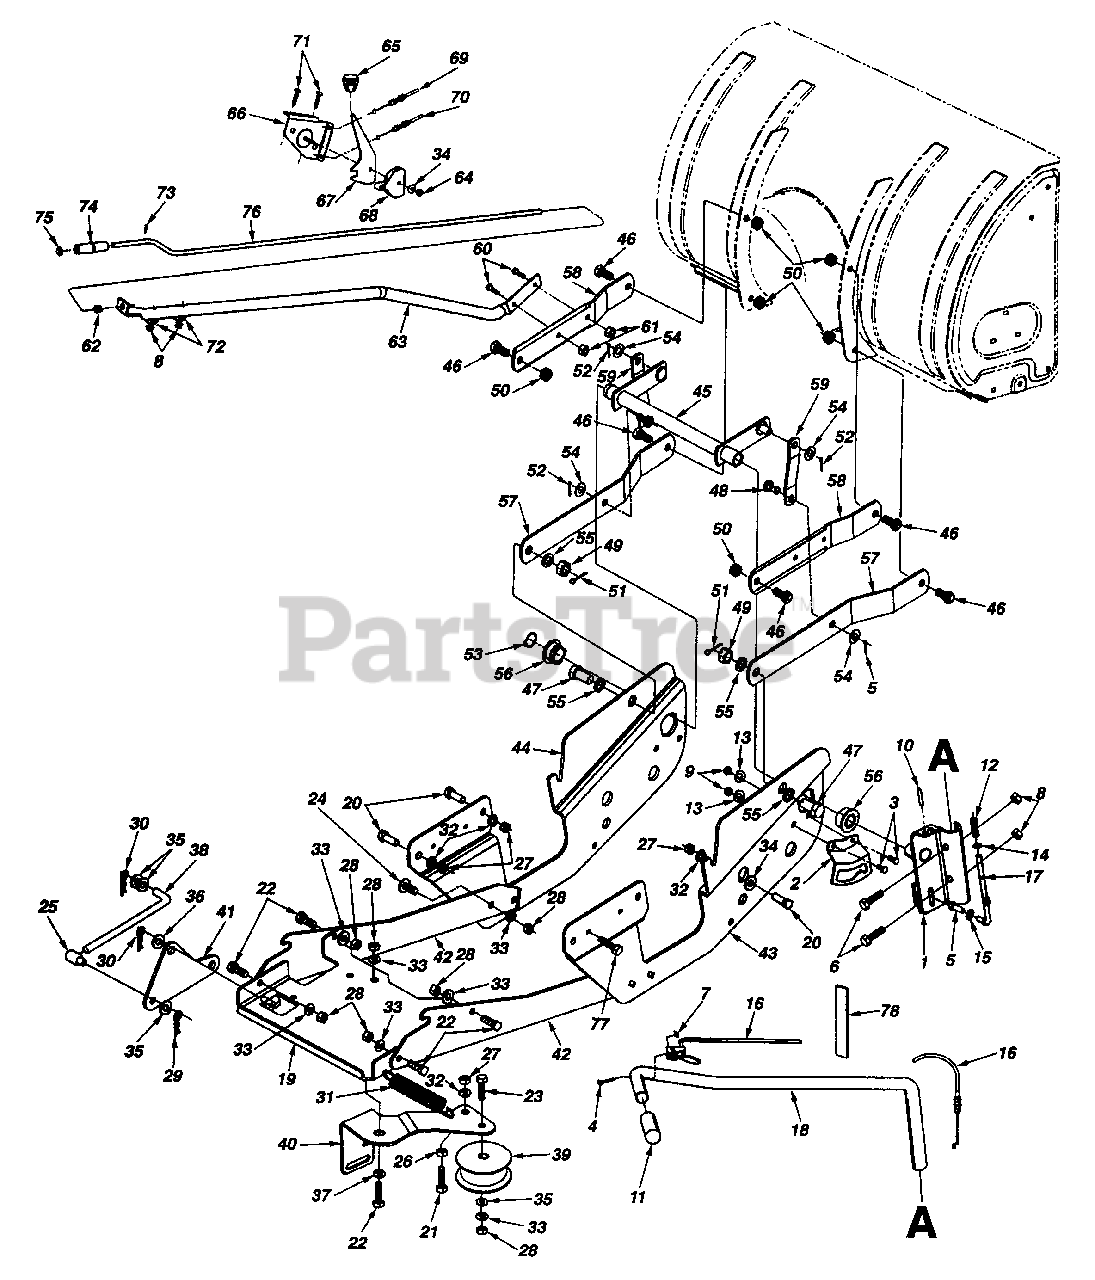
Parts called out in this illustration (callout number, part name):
4	Oval C-Sunk Scr. #10-24 x 1.36" Lg.
5	Hex Wash. Hd. Scr. 5/16-18 x .87" Lg.
6	Hex Bolt 5/16-18 x 1.75" Lg.
7	Flat Weld Nut #10-24 Thd.
8	Hex Flange L-Nut 5/16-18 Thd.
9	Hex Nut 5/16-18 Thd. (Gr. 5)
10	Spring Pin 1.5" Lg.
12	Ext. Spring 1.75" Lg.
13	L-Wash. 5/16" I.D.
14	Fl-Wash. .385" I.D. x .62" O.D.
15	Fl-Wash. .194" I.D. x .62" O.D.
16	Lift Cable
17	Lift Index Rod
18	Lift Handle Tube
21	Hex Bolt 5/16-18 x 2.25" Lg.
22	Hex Bolt 3/8-16 x 1" Lg.
23	Hex Bolt 3/8-16 x 2" Lg. (Gr. 5)
24	Carriage Bolt 3/8-16 x 1" Lg. (Gr. 5)
25	Ferrule 3/8-24 Thd.
26	Hex Jam Nut 5/16-18 Thd.
27	Hex Nut 5/16-18 Thd. (Gr. 5)
28	Hex Nut 3/8-16 Thd. (Gr. 5)
29	Hairpin Clip 1.42" Lg.
30	Hairpin Clip 1.62" Lg.
31	Ext. Spring 5.5" Lg.
32	L-Wash. 5/16" I.D.
33	L-Wash. 3/8" I.D.
34	Bell-Wash. .345" I.D. x .88" O.D.
35	Fl-Wash. .406" I.D. x .875" O.D.
36	Fl-Wash. .531" I.D. x 1" O.D.
37	Shoulder Spacer
38	Adj. Clutch Control Rod
39	Idler Pulley
47	Hex Bolt 5/8-18 x 1.25" Lg. (Gr. 5)
48	Lift Bracket Pin
49	Hex Slotted Nut 5/8-18 Thd.
50	Hex Cent. L-Nut 1/2-13 Thd. (Gr. 5)
51	Cotter Pin 1.25" Lg.
52	Cotter Pin .75" Lg.
53	Snap Ring
54	Fl-Wash. .51" 1.9. x 1" O.D.
55	Fl-Wash. 5/8" I.D. x 1" O.D.
56	Flange Bearing w/Flats
61	Hex Flange L-Nut 5/16-18 Thd.
62	Plastic Bushing
65	Knob
68	Cable Guide
69	Chute Control Cable w/Clip
70	Chute Control Cable
71	Carriage Bolt 5/16-18 x 1.5" Lg.
72	Saddle Wash. .32" I.D.
73	Roll Pin .63" Lg.
74	Chute Crank Knob
75	Push Cap 3/8" Rod
76	Chute Crank Rod
77	Hex Wash. Hd. Tap Scr. 1/4-20 x .75" Lg.
78	Cable Tie
